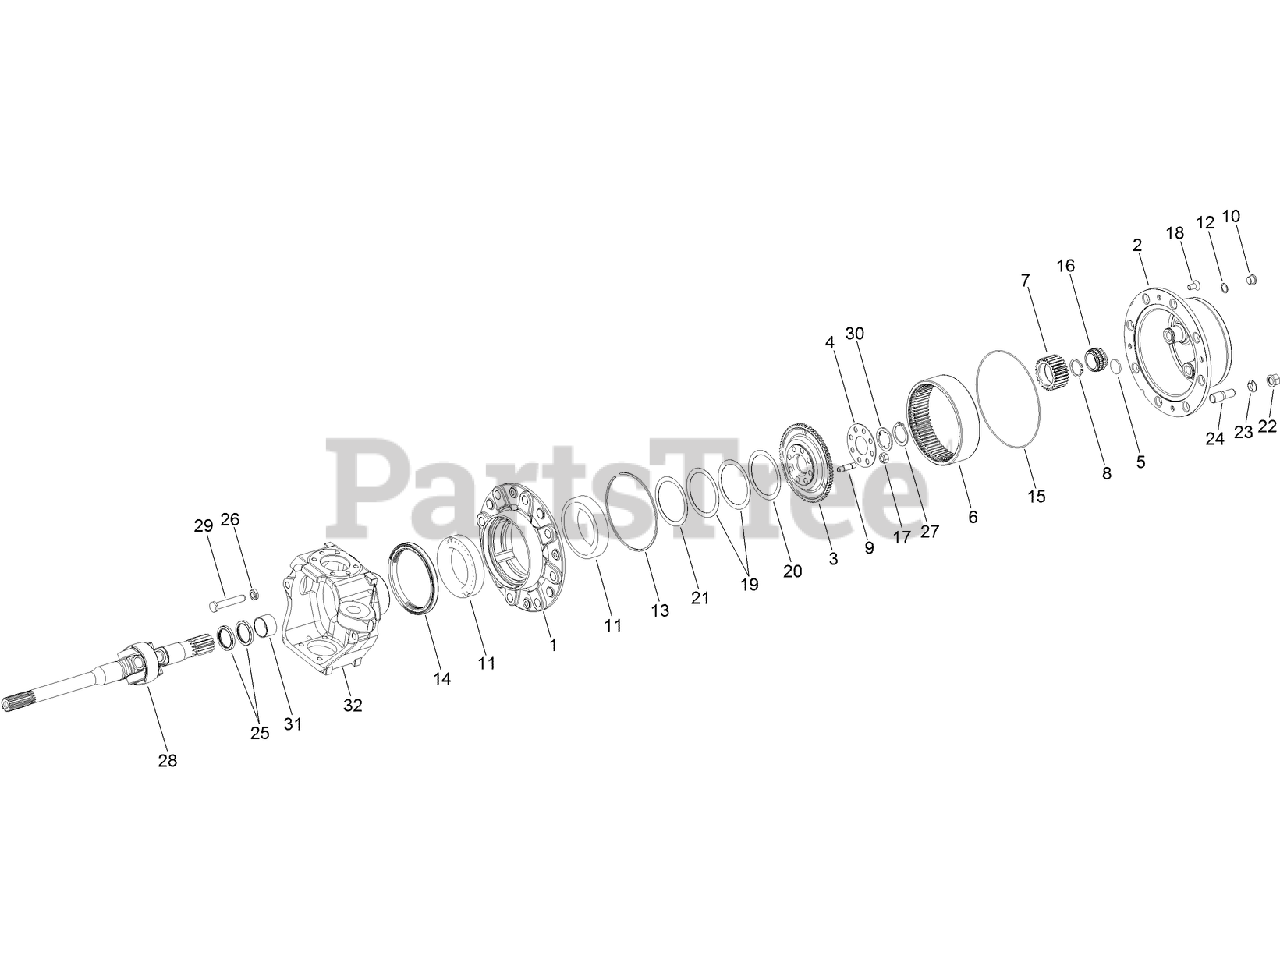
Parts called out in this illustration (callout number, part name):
1	HUB-WHEEL
2	HUB-PLANETARY
3	FLANGE-CROWN
4	RING-CROWN
5	SHIM-CROWN, WHEEL
6	WHEEL-CROWN
7	GEAR-PLANETARY
8	RING-SNAP
9	BOLT-STUD
11	BEARING
12	WASHER-COPPER
13	RING-RETAINING
14	SEAL-OIL
15	O-RING
16	BEARING-ROLLER
19	SHIM (0.2)
20	SHIM (0.1)
21	SHIM (0.35)
23	WASHER-ELASTIC
24	BOLT-STUD
25	SEAL-OIL
27	RING-SNAP
28	SHAFT-DRIVE
29	SCREW-END, STEERING
30	SHIM-CROWN
31	BUSHING
32	JOINT-RH, ARTICULATED
